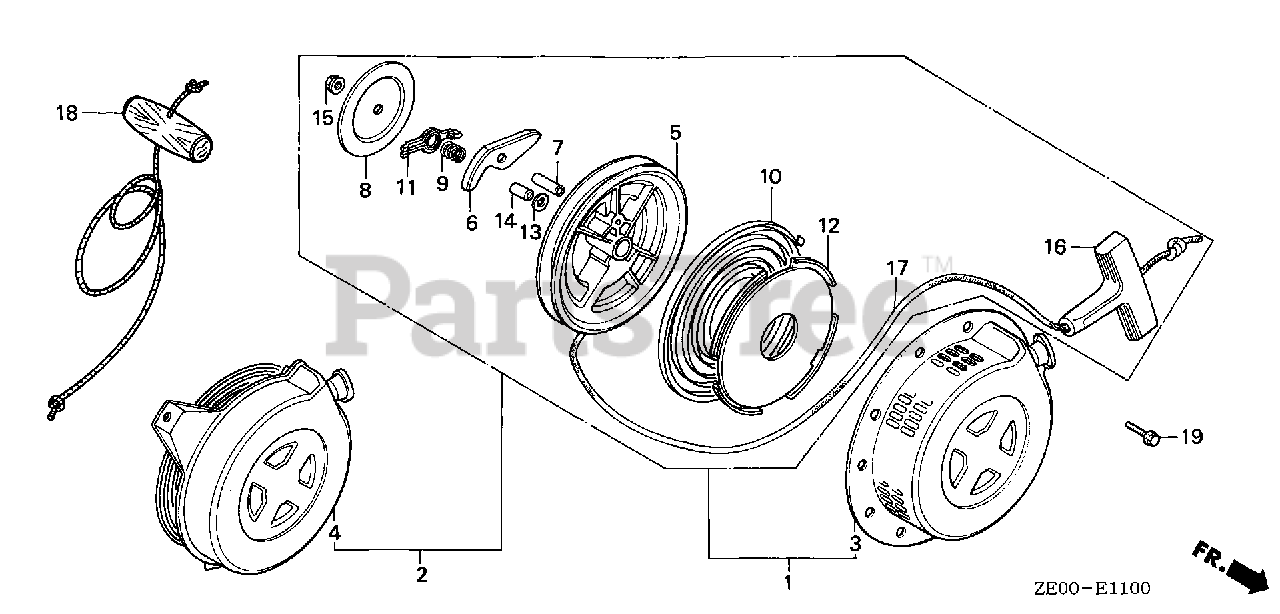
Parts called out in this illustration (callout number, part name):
1	STARTER ASSY., RECOIL *R280* (POWER RED)
3	CASE, RECOIL STARTER *R280* (POWER RED)
5	PULLEY, RECOIL STARTER
6	RATCHET, STARTER
7	PIN, STARTER RATCHET
8	PLATE, FRICTION
9	SPRING, FRICTION
10	SPRING, RECOIL STARTER
11	GUIDE, RATCHET
12	CASE, RECOIL STARTER SPRING
13	WASHER, STARTER
14	SHAFT, SUB
15	NUT (NOT AVAILABLE)
16	KNOB, RECOIL STARTER
17	ROPE, RECOIL STARTER
19	BOLT, FLANGE (6X8)
